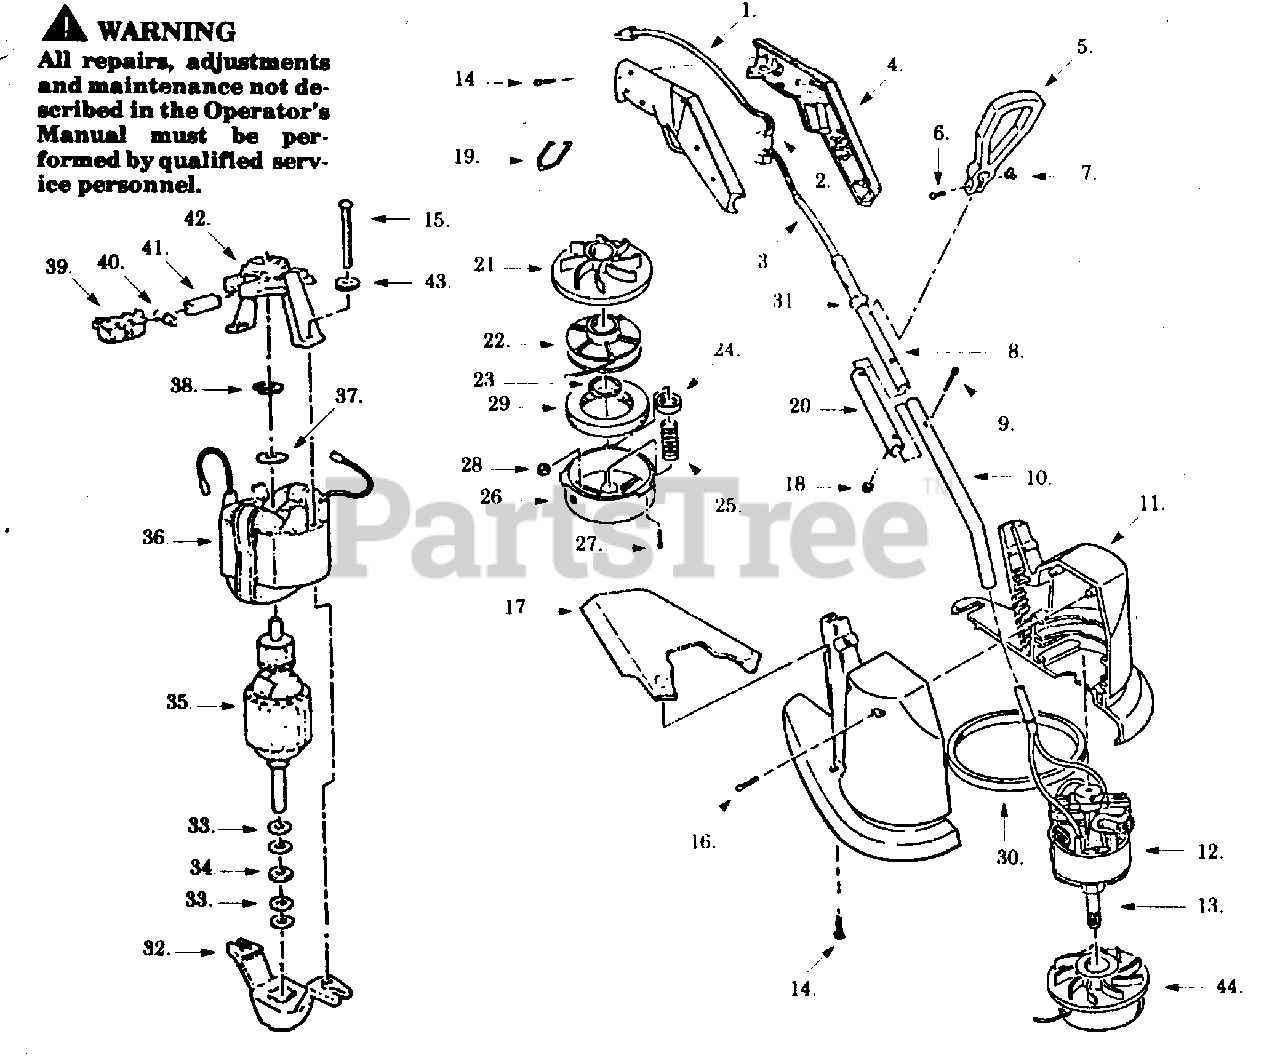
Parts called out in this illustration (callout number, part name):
1	Power Cord
4	R.H./L.H. Handle
5	Assist Handle
7	Wing Nut
8	Upper Tube
10	Lower Tube
11	Motor Housing
13	Shaft Adapter
17	Guard Ass'y.
20	Outer Tube
21	Rear Plate
22	Spool & Line
24	Adapter Nut
26	Hub Ass'y.
27	Cotter Pin
29	Foam Pad
32	Endbell Ass'y. (Drive)
34	Spring Washer
35	Armature Ass'y.
36	Field Ass'y.
37	Slinger Washer
38	Retaining Ring
39	Brush Holder
40	Brush Spring
42	Endbell Ass'y. (Brush)
43	Lockwasher
44	Cutting Head Ass'y.
